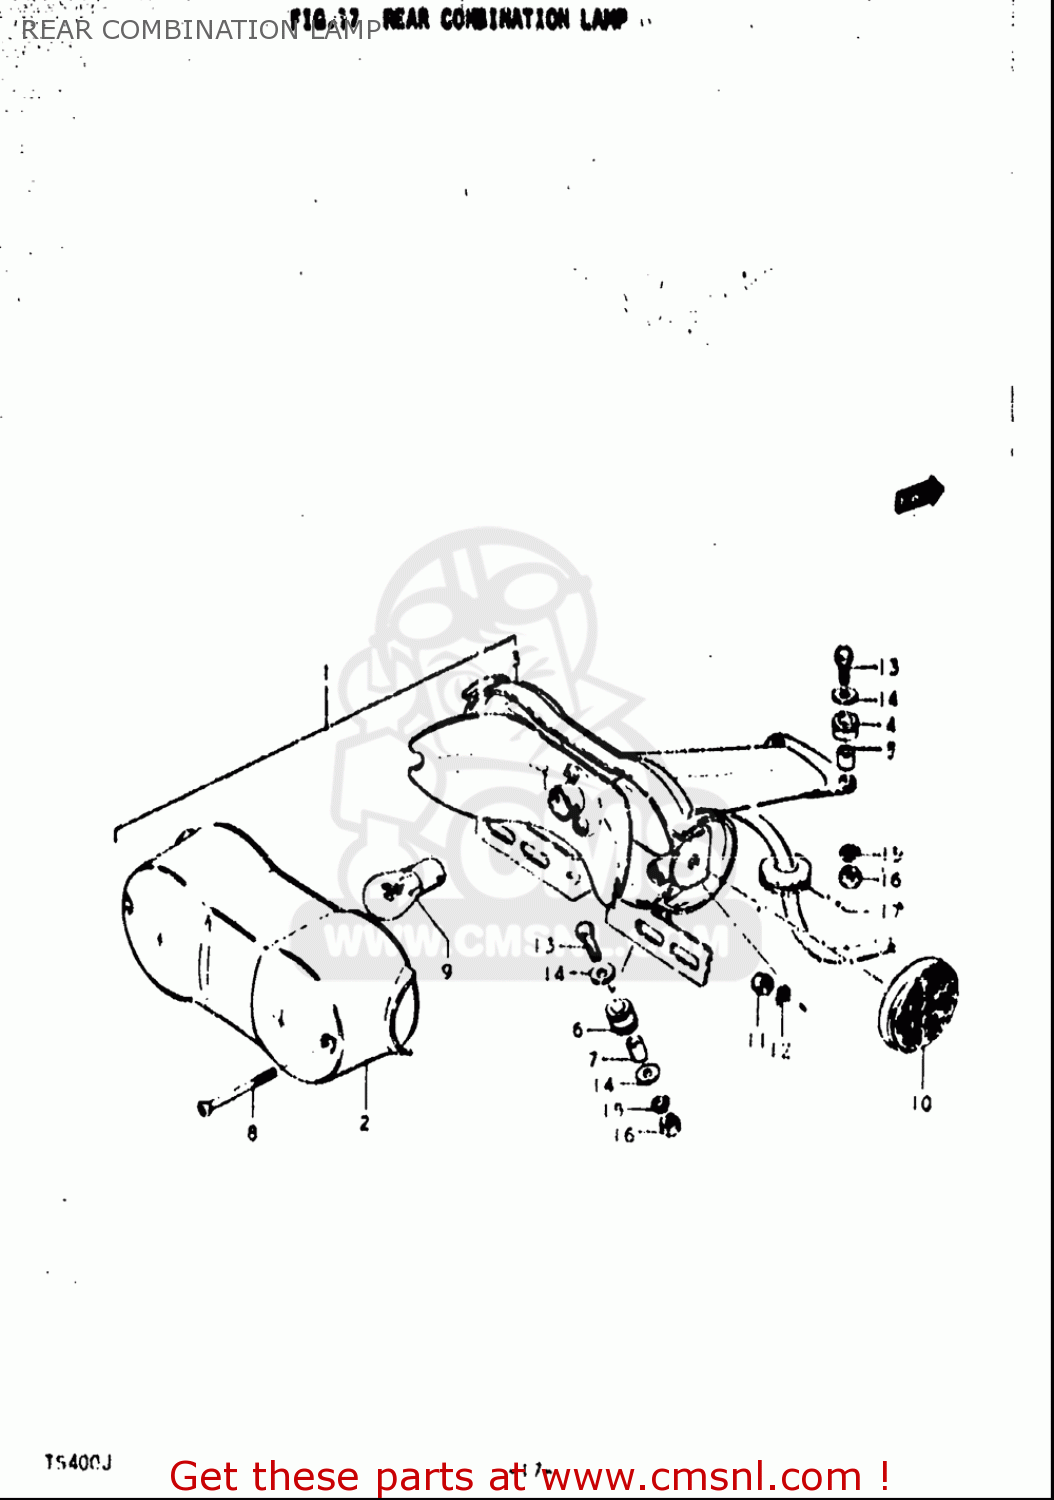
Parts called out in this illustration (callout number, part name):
2	LENS,RR COMBINATION LAMP
4	CUSHION
5	SPACER
6	CUSHION
7	SPACER
8	SCREW
9	BULB(12V23W)
11	NUT
12	WASHER,LOCK
13	BOLT
14	WASHER(6.5X20X1.2)
15	WASHER,LOCK
16	NUT
17	GROMMET
